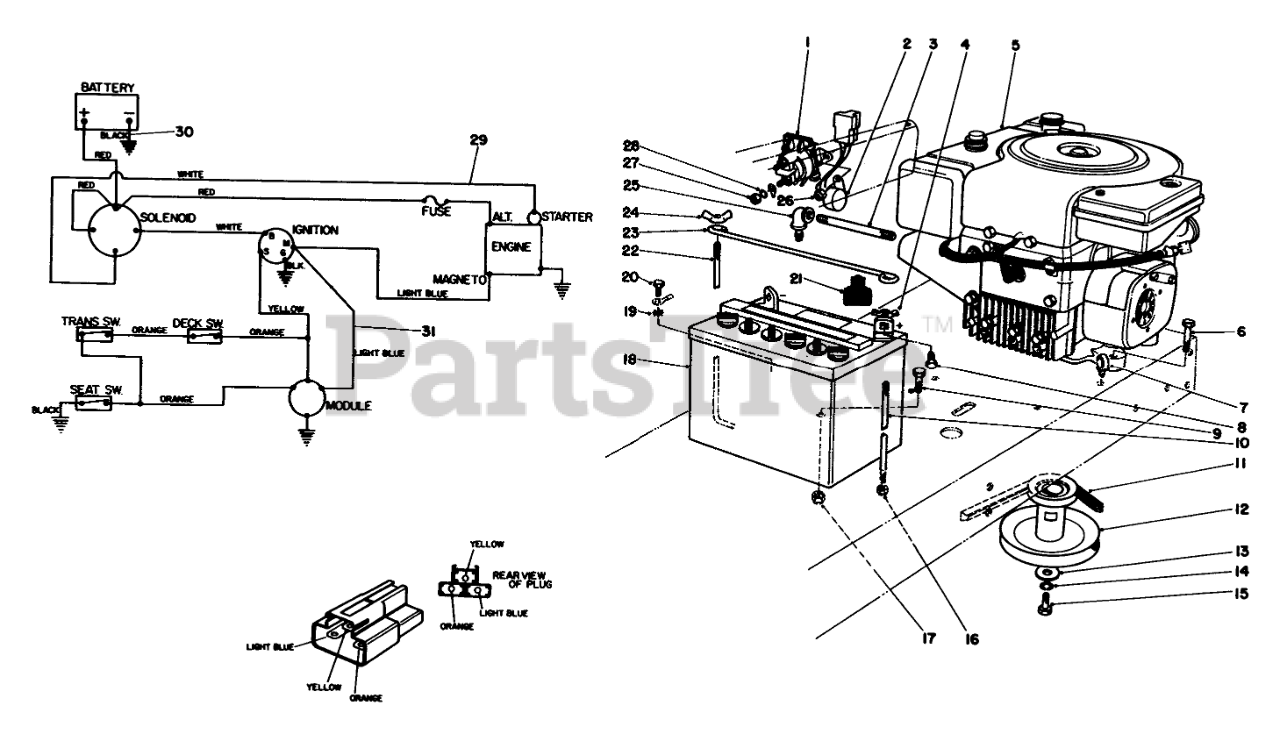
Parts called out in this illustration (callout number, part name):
1	SOLENOID
2	Module Interlock
3	NIPPLE
4	NUT-WING
5	Engine
6	SCREW-HH
7	Clip-Cable
8	SCREW-HH
9	SCREW-HH
10	BATTERY BOLT
11	V-BELT, TRACTION
12	PULLEY
13	WASHER
14	WASHER-LOCK
15	SCREW-HH
16	NUT-KEPS
17	NUT-LOCK, CONE
18	Battery
19	WASHER-LOCK, INTERNAL
20	SCREW-HHF
21	BOOT-TERMINAL
22	ROD-SUPPORT, BATTERY
23	BATTERY HOLD DOWN
24	NUT-WING
25	ELBOW-90 DEGEE
26	NUT-LOCK, CONE
27	NUT-JAM
28	WASHER-LOCK
29	Wiring Harness
30	Wire-Battery to Ground
31	Wiring Harness
